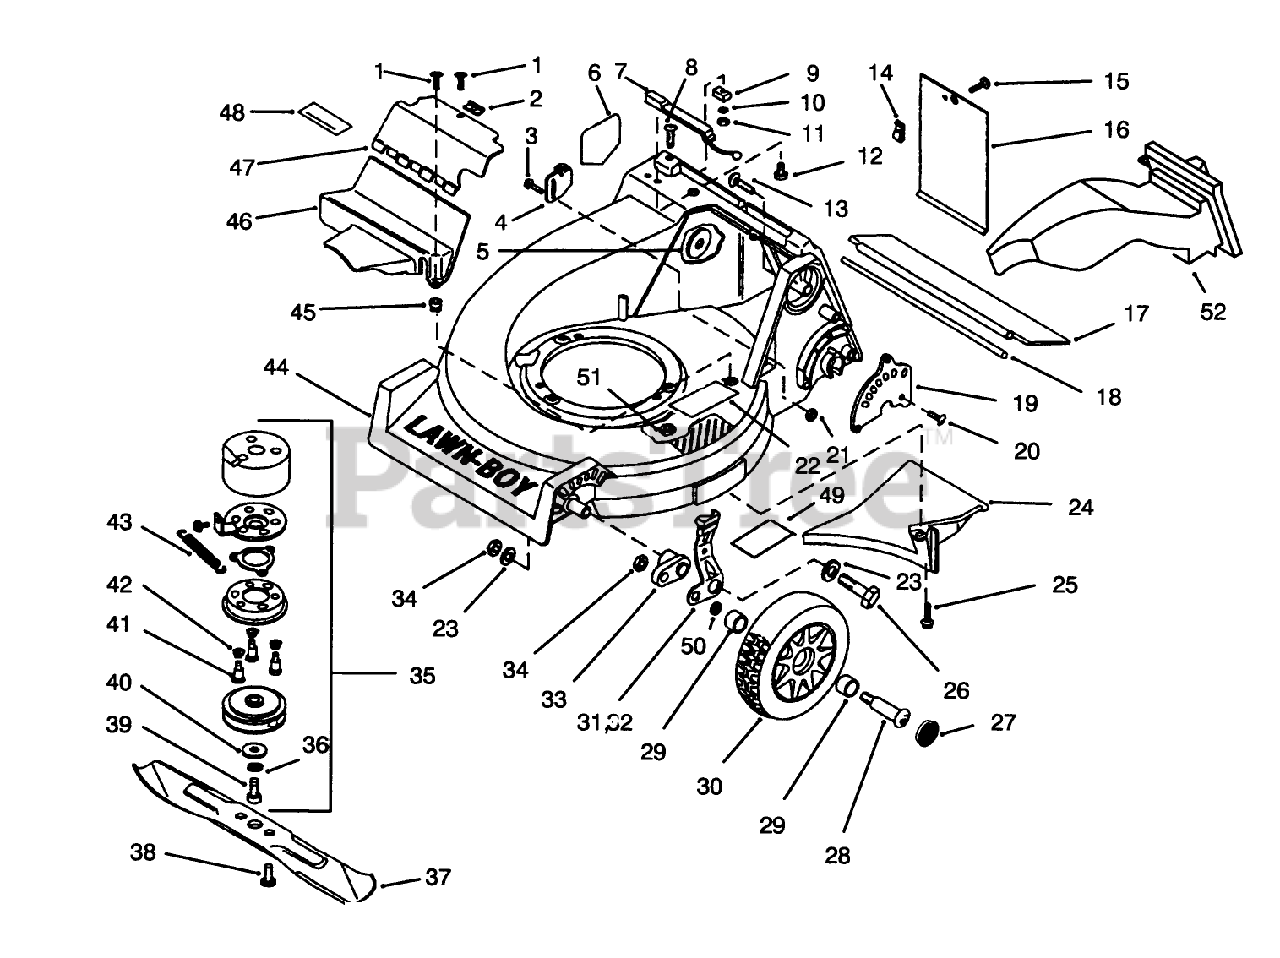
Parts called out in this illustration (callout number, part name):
2	NUT-SPEED
4	ANCHOR-CABLE
6	DECAL-DANGER
14	SPEED NUT LARSON
15	SCREW-CROSS RECESS
16	DOOR-ACCESS ELECT.
17	SHIELD - TRAILING
20	SCREW-BHTF
21	NUT-LOCK, NI
23	WASHER-PLAIN
24	CHUTE BAFFLE NYL
25	SCREW-HWH
28	BOLT-SHOULDER
30	WHEEL ASM
31	KNOB & SPRING CMS
33	ARM HGT ADJ *BLACK
34	NUT-JAM, LOCKING
38	SCREW SEMS
41	SCREW,SHOULDER SM
44	HOUSING ASM.
45	NUT-CLIP
49	DECAL-INSTRUCTION, SAFETY
51	NUT-LOCK, NI
